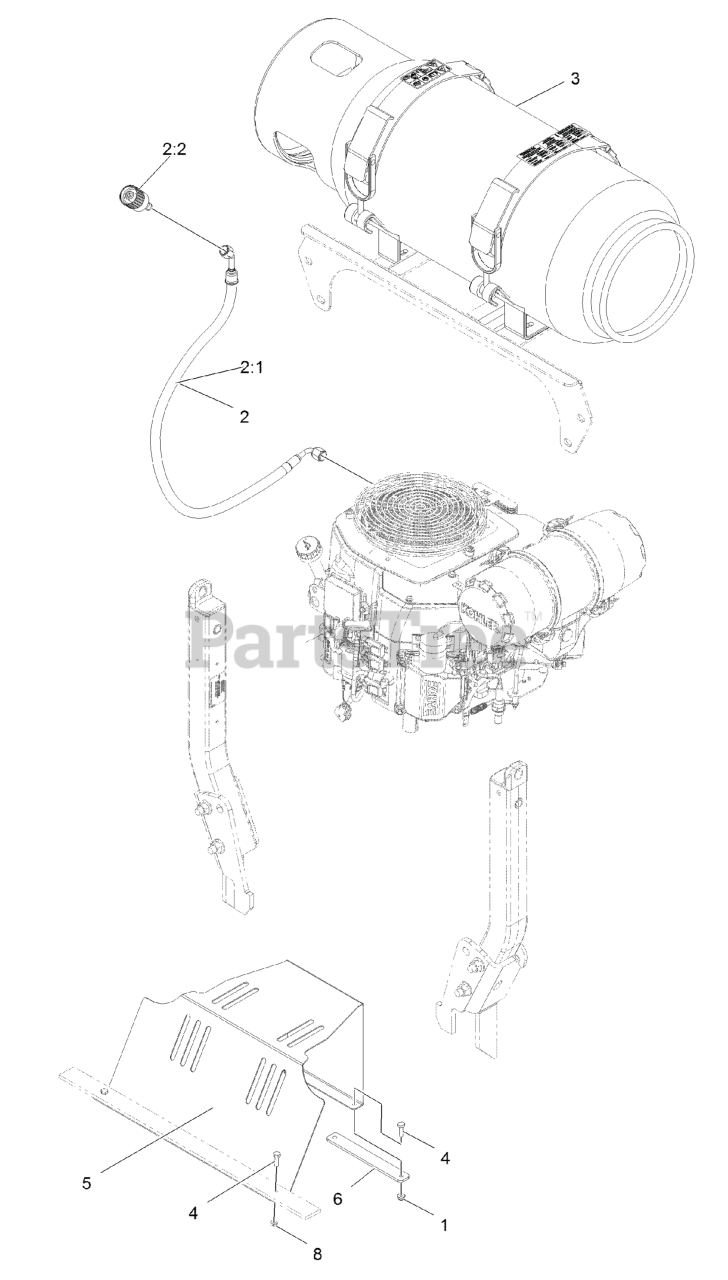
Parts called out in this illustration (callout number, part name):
2	LPG HOSE ASM
2:1	HOSE ASM, LPG
2:2	CONNECTOR-LP, STRAIGHT
3	TANK-LPG
4	SCREW-HH
5	SHEILD-FAN
8	NUT-JAM
